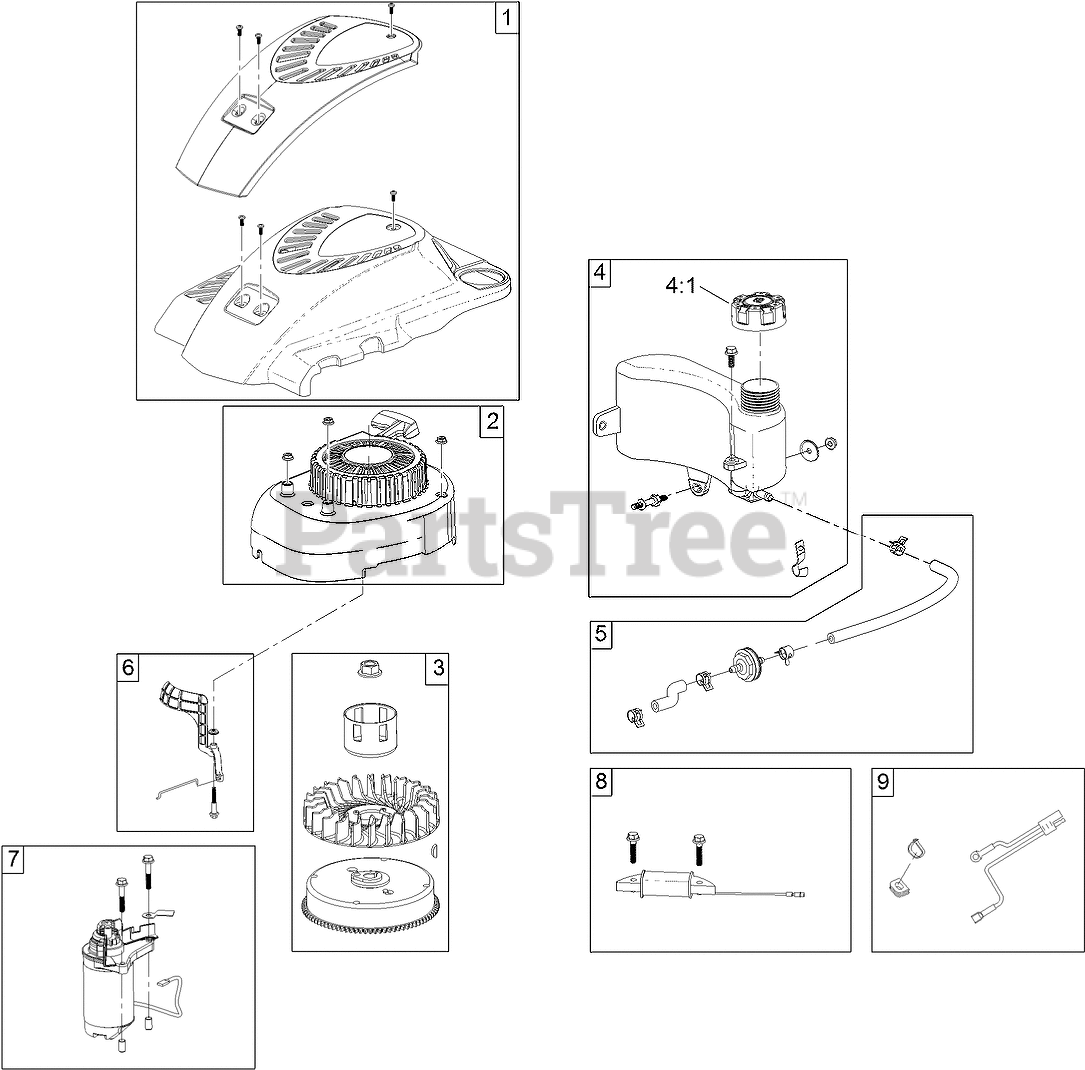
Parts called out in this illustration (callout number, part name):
1	Shroud ASM
2	SHROUD AND RECOIL ASM
3	FLYWHEEL AND FAN KIT
4	FUEL TANK KIT (CAP AND HARDWARE)
4:1	CAP-FUEL
5	FUEL LINE KIT
6	AIR VANE CHOKE KIT
7	STARTER KIT
8	ALTERNATOR KIT
9	WIRE HARNESS KIT
